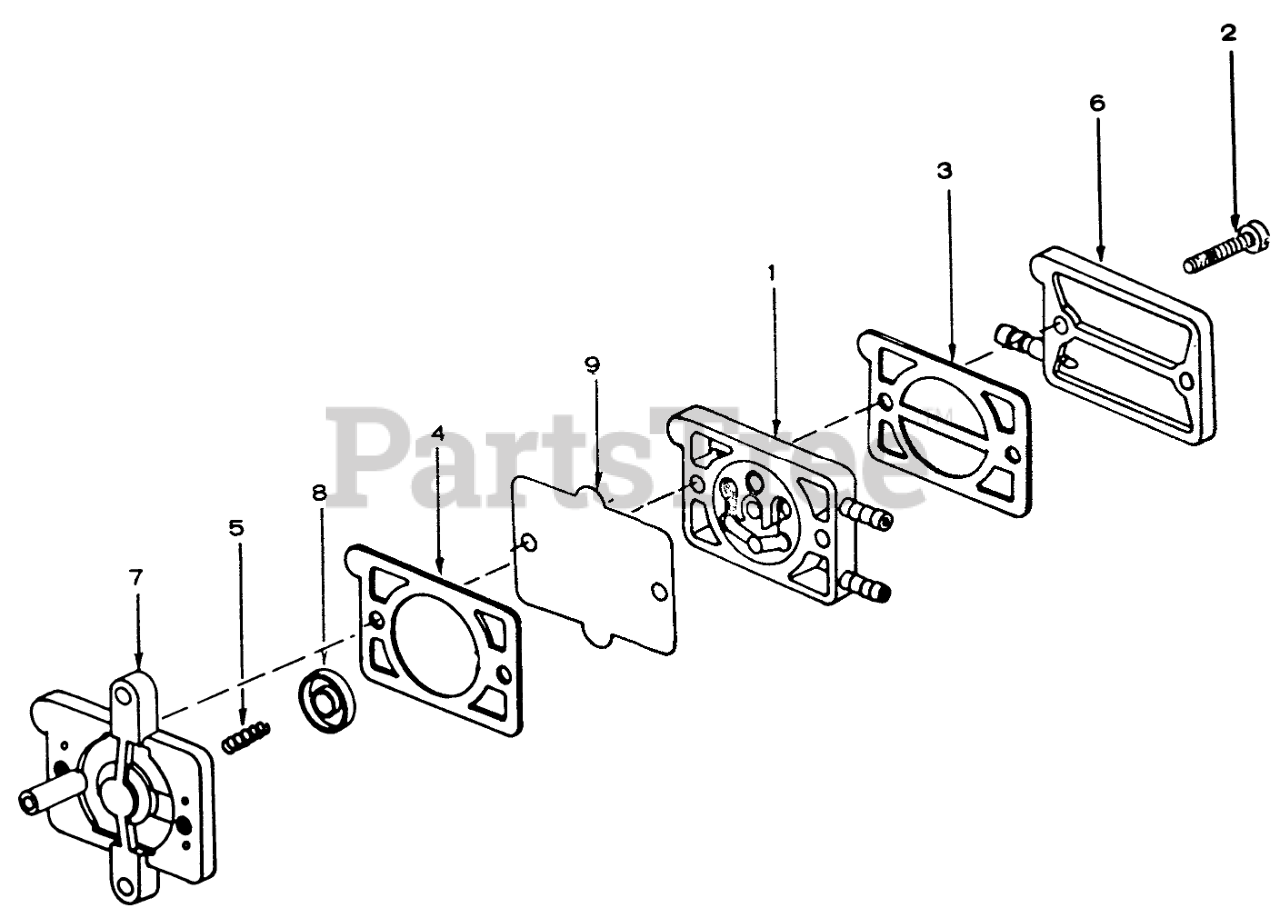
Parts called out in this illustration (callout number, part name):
1	Valve Plate Assy
2	Screw-Pump Cover
3	Gasket-Cover To Valve Plate
4	Gasket-Base To Diaphram
5	Spring-Pump To Diaphram
6	Cover-Pump
7	Base Pump
8	Plate-Pump Spring
9	Pump Diaphragm
